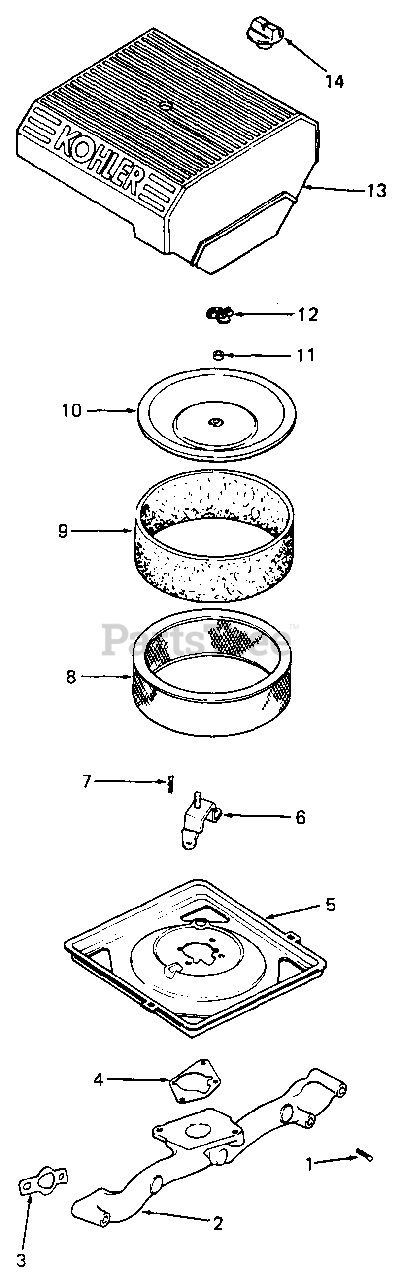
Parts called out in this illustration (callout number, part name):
1	Screw, M6 x 1.0 x 18
2	Manifold, Intake
3	Gasket, Intake Manifold
4	Gasket, Air Cleaner Base
5	Base, Air Cleaner
6	Bracket, Air Cleaner
7	Screw, M6 x 1.0 x 13
8	Element, Air Cleaner
9	Element, Pre-Cleaner
10	Cover, Inner Air Cleaner
11	Seal, Air Intake
13	Cover, Air Cleaner
14	Knob, Cover
